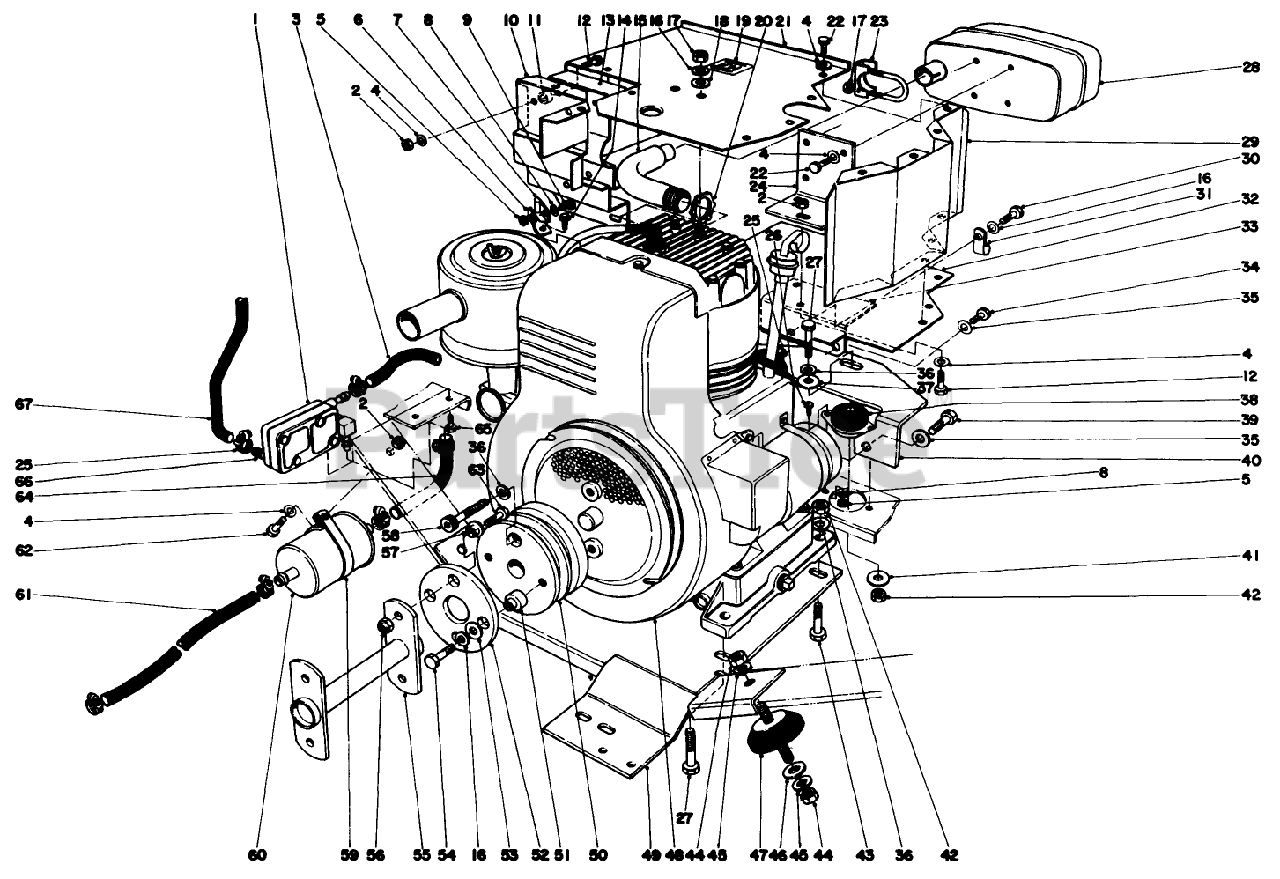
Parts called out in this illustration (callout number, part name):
1	FUEL PUMP
2	NUT-HEX
3	PULSE LINE
4	WASHER-LOCK
5	NUT-HEX
6	BODEN CLIP BRKT
7	CLAMP-BODEN
8	WASHER-LOCK
9	SCREW-PPH
10	REAR SHIELD WA B
11	SPACER-HUB, AUGER
12	SCREW-HH
13	Shield Exhaust
14	SCREW
15	EXHAUST PIPE
16	Lockwasher
17	NUT-HEX
18	WASHER-PLAIN
19	Decal-Hot
20	Locknut
21	Top Heat Shield
22	SCREW-HH
23	MUFFLER CLAMP
24	MUFFLER BRKT B
25	CLAMP-HOSE
26	10-24 X 5/8 PAN HD MS
27	SCREW-HH
28	Muffler
29	LH SIDE HT SHIELD B
30	SCREW-HH
32	Bottom Heat Shield
33	Bracket Heat Shield
34	SCREW-HH
35	WASHER-LOCK
36	WASHER-LOCK
37	WASHER-FLAT
38	RUBBER MOUNT
39	SCREW-HH
40	REAR ENGINE MT B
41	WASHER
42	NUT-HEX
43	SCREW-HH
44	NUT-HEX
45	WASHER-LOCK
46	WASHER-FLAT
47	RUBBER MOUNT
48	Engine
49	ENGINE BASE WA
50	ENGINE PULLEY BO
51	SPACER-COUPLING, RUBBER
52	Coupling Rubber
53	WASHER-FLAT
54	SCREW-HH
55	Drive Coupling
56	NUT-HEX
57	SPACER-COUPLING
58	SCREW-HSH
59	HOSE CLAMP
60	FiIter Gas
61	HOSE-FUEL
62	SCREW-HH
63	SCREW-HH
64	HOSE-FUEL
65	Screw-Outlet
66	FITTING
67	FUEL LINE
